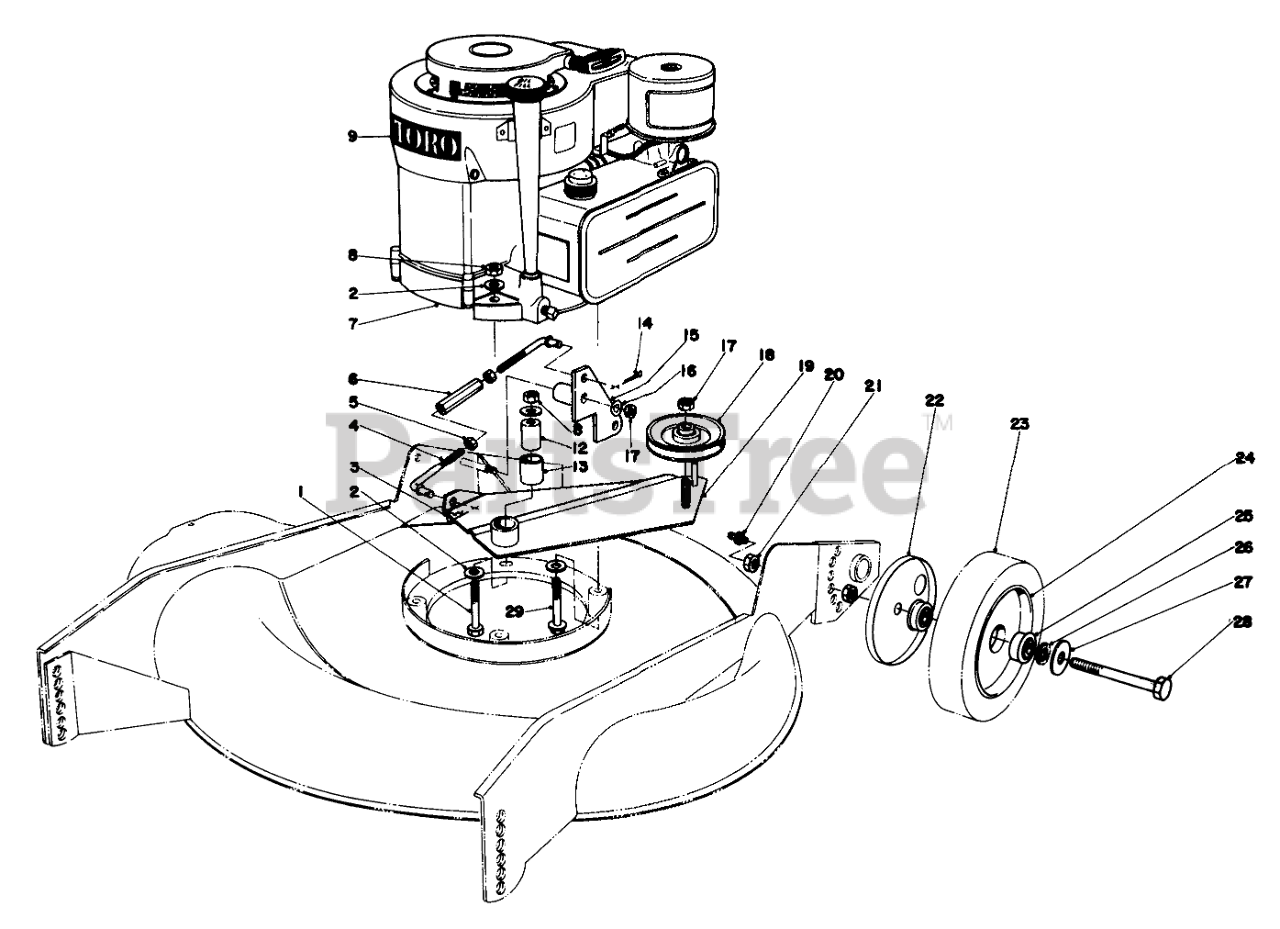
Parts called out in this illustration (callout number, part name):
1	SCREW-HH
2	WASHER-PLAIN
3	HAIRPIN COTTER
4	Link-Control Rod
5	NUT-KEPS
6	CONTROL ROD SLEEVE
7	Engine
8	Nut
9	Decal Toro
12	Pedestal
13	BUSHING
14	PIN-COTTER
15	BELL CRANK WA
16	WASHER-FLAT
17	NUT-HEX
18	IDLER PULLEY R
19	Idler Arm (Incl. Ref. #13)
20	FITTING-GREASE
21	NUT-HEX
22	WHEEL COVER
24	Wheel & Tire Assembly, Rear (Incl. Ref. #23 & 25)
25	BEARING-BALL
26	FELT WASHER
27	WASHER-FLAT
28	WHEEL BOLT REAR
29	3/8-16 X 2-3/4 CAPSCR
